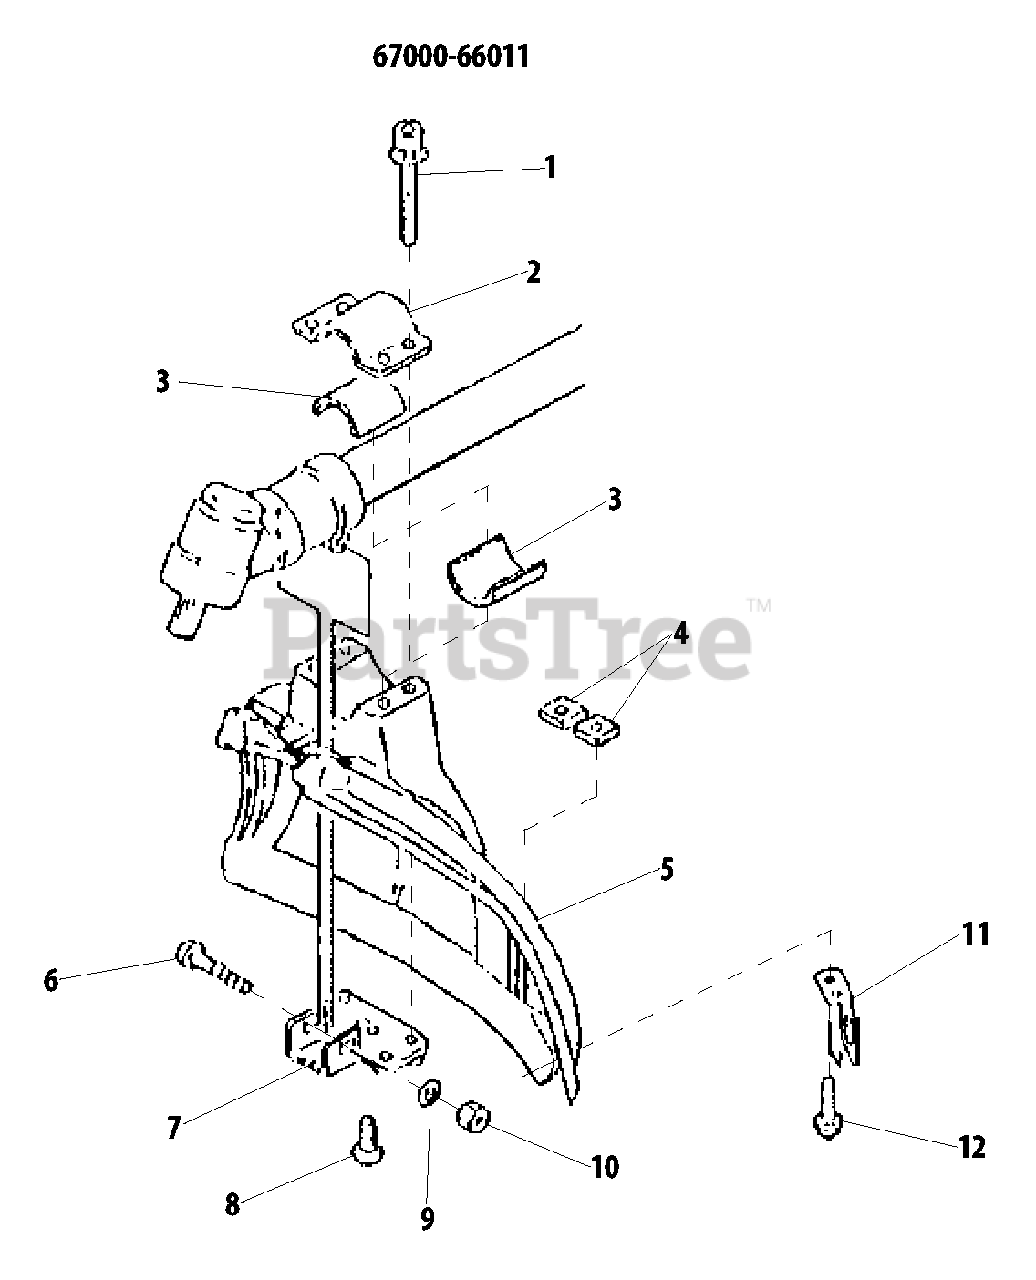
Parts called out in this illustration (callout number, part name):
1	BOLT M5×45
2	CLAMP, UPPER
3	SPACER
4	NUT M5
5	SHIELD, DEBRIS
6	BOLT M5×35
7	PLATE, SHIELD MOUNTING
8	SCREW HILO 4×10
9	WASHER 5 MM
10	NUT M5
11	CUTTER
12	BOLT M5×16
67000-66011	DEBRIS SHIELD ASSY
